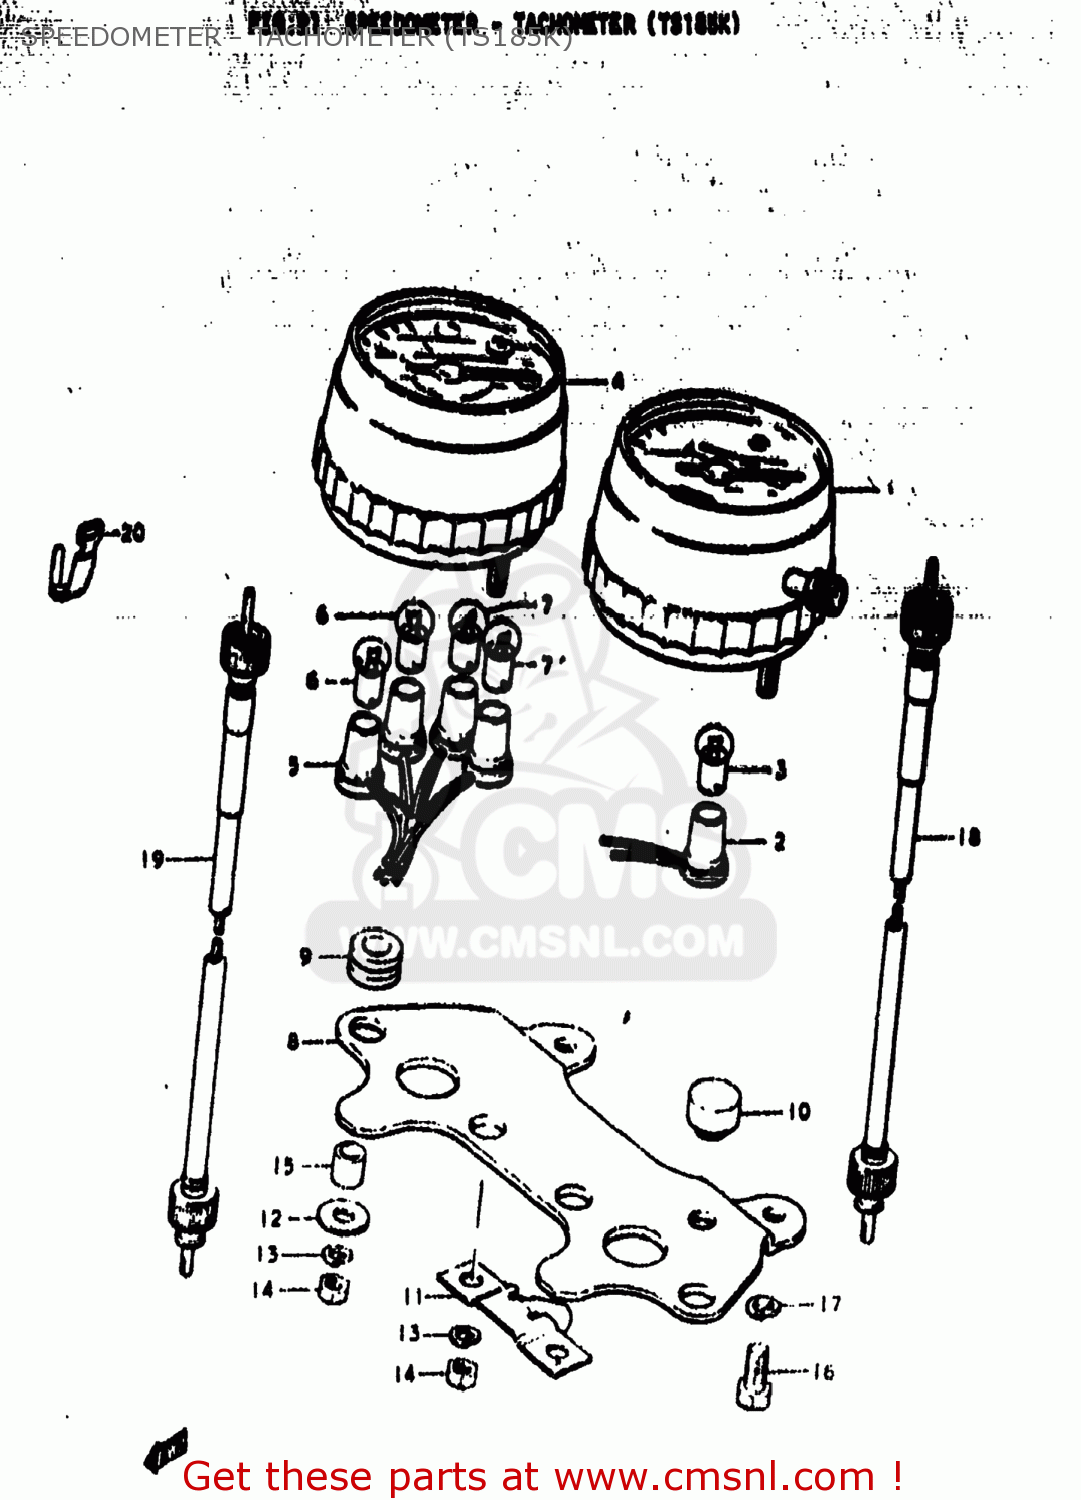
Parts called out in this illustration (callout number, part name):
1	SPEEDOMETER ASSEMBLY
2	SOCKET,METER
3	BULB(6V/3W)
4	TACHOMETER ASSEMBLY
5	SOCKET,TACHOMETER
6	BULB(6V/3W)
7	BULB(6V1.7W,STANLEY,A61A)
8	BRACKET,METER
9	CUSHION
10	CUSHION,METER
11	COVER,METER,UNDER
12	WASHER (5.5X16X1.2)
13	LOCK WASHER
14	NUT
15	SPACER,METER NO.2
16	BOLT
17	LOCK WASHER
18	CABLE ASSEMBLY,SPEEDOMETER
19	CABLE ASSEMBLY,TACHOMETER
20	CLAMP
